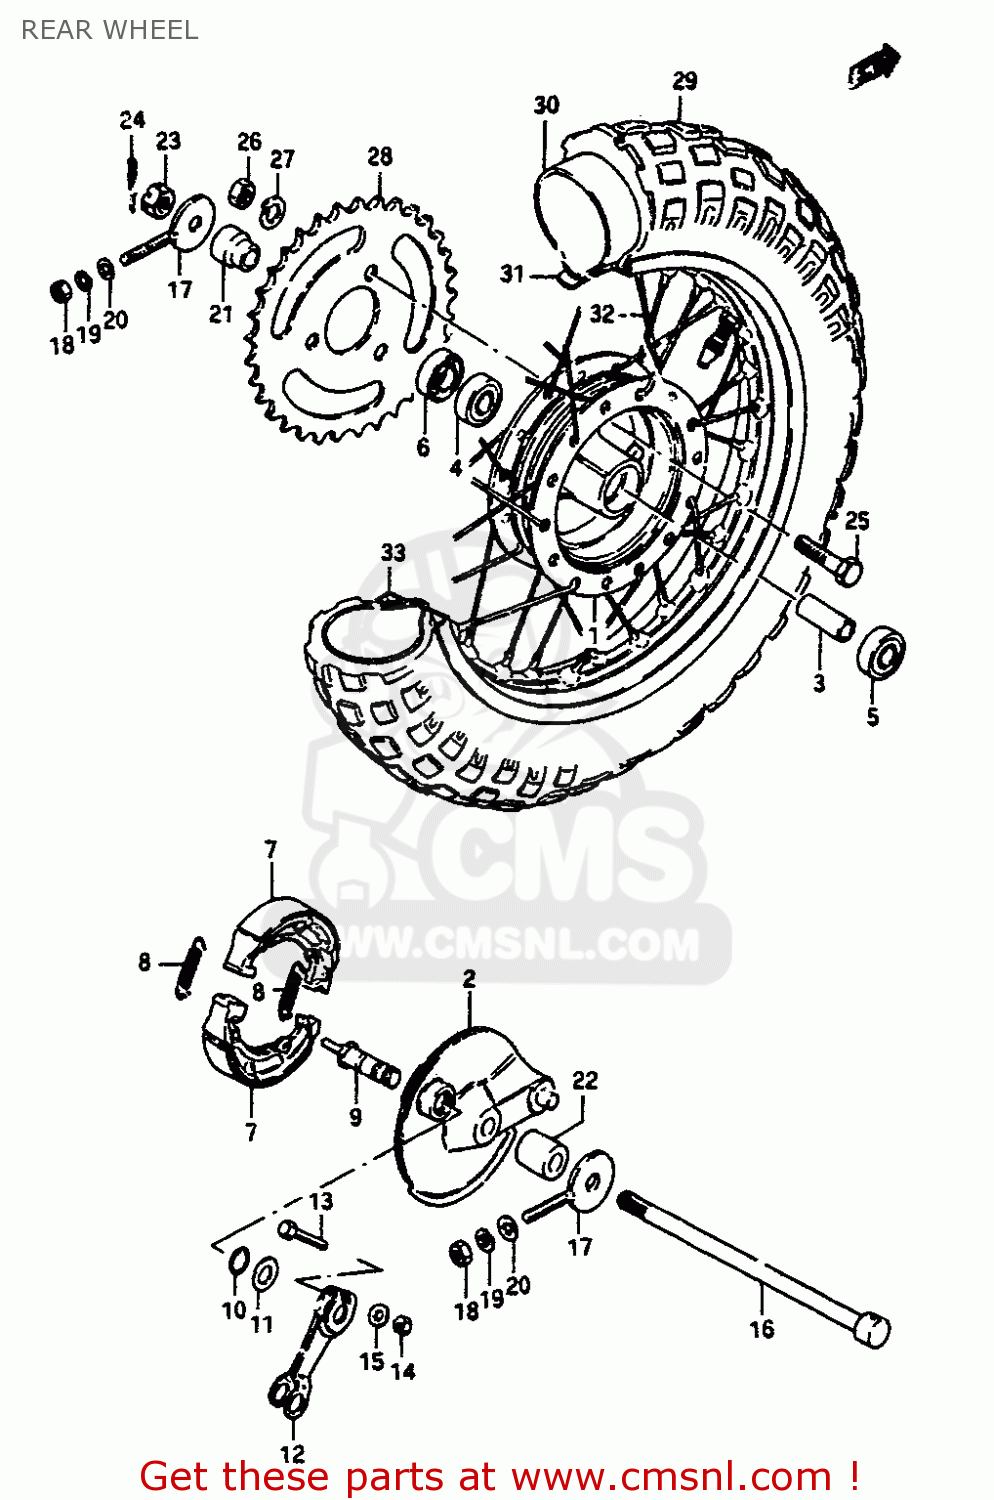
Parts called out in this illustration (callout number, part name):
1	HUB,RR WHEEL
2	PANEL,RR BRAKE ANCHOR
3	SPACER (10.2X16X55)
4	BALL BEARING K
5	BEARING
6	SEAL,OIL(15X27X6)
7	SHOE,BRAKE
8	SPRING(L:34)
9	CAM,FRONT BRAKE
10	O RING(D:2.4,ID:9.8)
11	WASHER (10.5X18X1)
12	LEVER,RR BRAKE CAM
13	BOLT
14	NUT
15	WASHER
16	AXLE,RR
17	ADJUSTER,CHAIN
18	NUT 6MM
19	WASHER,LOCK
20	WASHER
21	SPACER,RR AXLE,L
22	SPACER,RR AXLE,R
23	NUT
24	PIN 20X20
25	BOLT
26	NUT
27	LOCK WASHER
28	SPROCKET,RR
29	TIRE
30	TUBE,INNER
31	PROTECTOR,INNER TUBE
32	SPOKE SET,RR
33	RIM,WHEEL
